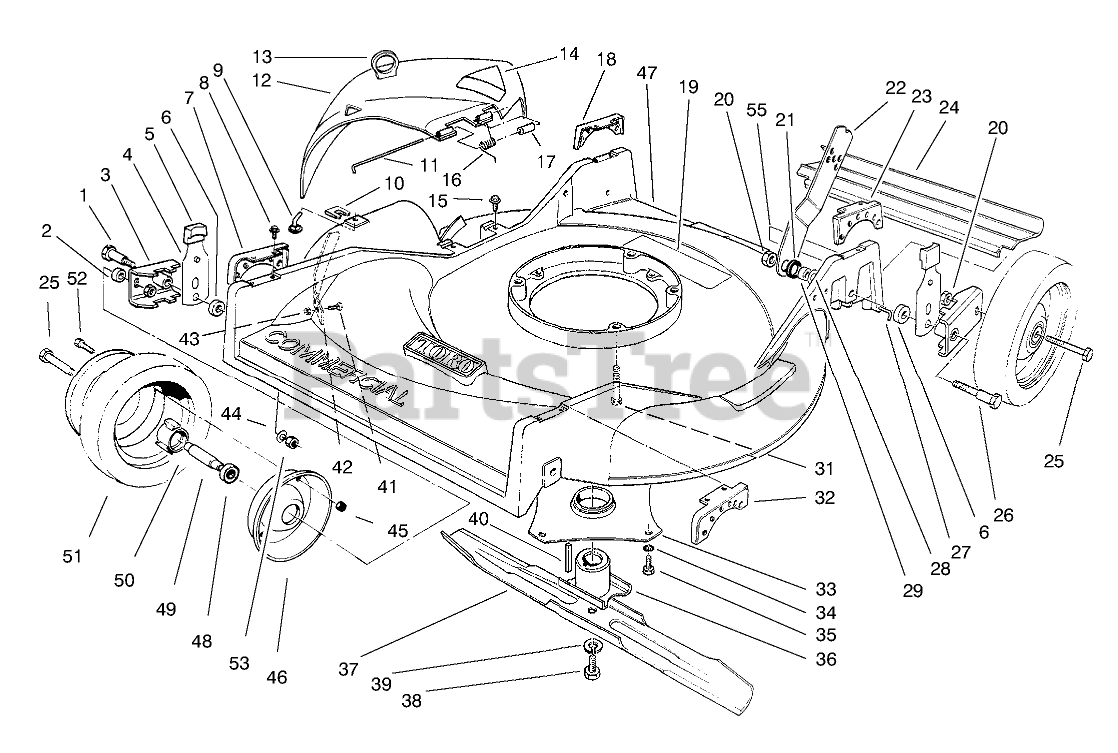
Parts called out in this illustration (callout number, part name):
1	PIVOT SCREW
2	SPACER-WHEEL
3	PIVOT ARM
4	SPRING ARM ASM-FRONT
5	KNOB-ARM
6	SPACER-PIVOT
7	FRT RIGHT QUAD
8	SCREW-HWHTF
9	BAG CHUTE PIN
10	BAG CHUTE CLIP PIN
11	DEFLECTOR HINGE PIN
12	Deflector (Incl. Ref. #14)
13	LIFT LOOP
14	DECAL-DANGER
15	SCREW-HWH
16	DEFLECTOR SPRING
17	SLEEVE
18	REAR RIGHT QUAD
19	DECAL-INSTRUCTION, SAFETY
20	NUT-LOCK, NI
21	HANDLE LATCH SPACER
22	Latch-Handle
23	REAR LEFT QUAD
24	SHIELD - TRAILING
25	SCREW-HH
26	REAR PIVOT SCREW
27	SHIELD ROD
28	WASHER-BELLEVILLE
29	HANDLE LATCH SPACER
30	DECAL-BLADE
31	Screw-Flange Head
32	FRT LEFT QUAD
33	CRNKSHFT PROTECT ASM
34	WASHER-LOCK, INTERNAL
35	SCREW-HWHTF
36	RETAINER-BLADE
37	Blade
38	SCREW-HH
39	WASHER-LOCK
40	KEY-SQUARE
41	SCREW-CARR
42	Bar-Safety
43	NUT-LOCK, NI
44	WASHER-BELLEVILLE
45	NUT-LOCK, NI
46	Wheel-Half
47	Housing (Incl. Ref. #19, & 55)
48	BEARING-WHEEL
49	SPACER-BEARING
50	HUB-BEARING
52	SCREW-HH
53	NUT-LOCK, CONE
54	DECAL-DANGER DEFLECTOR
55	DECAL-WARNING
